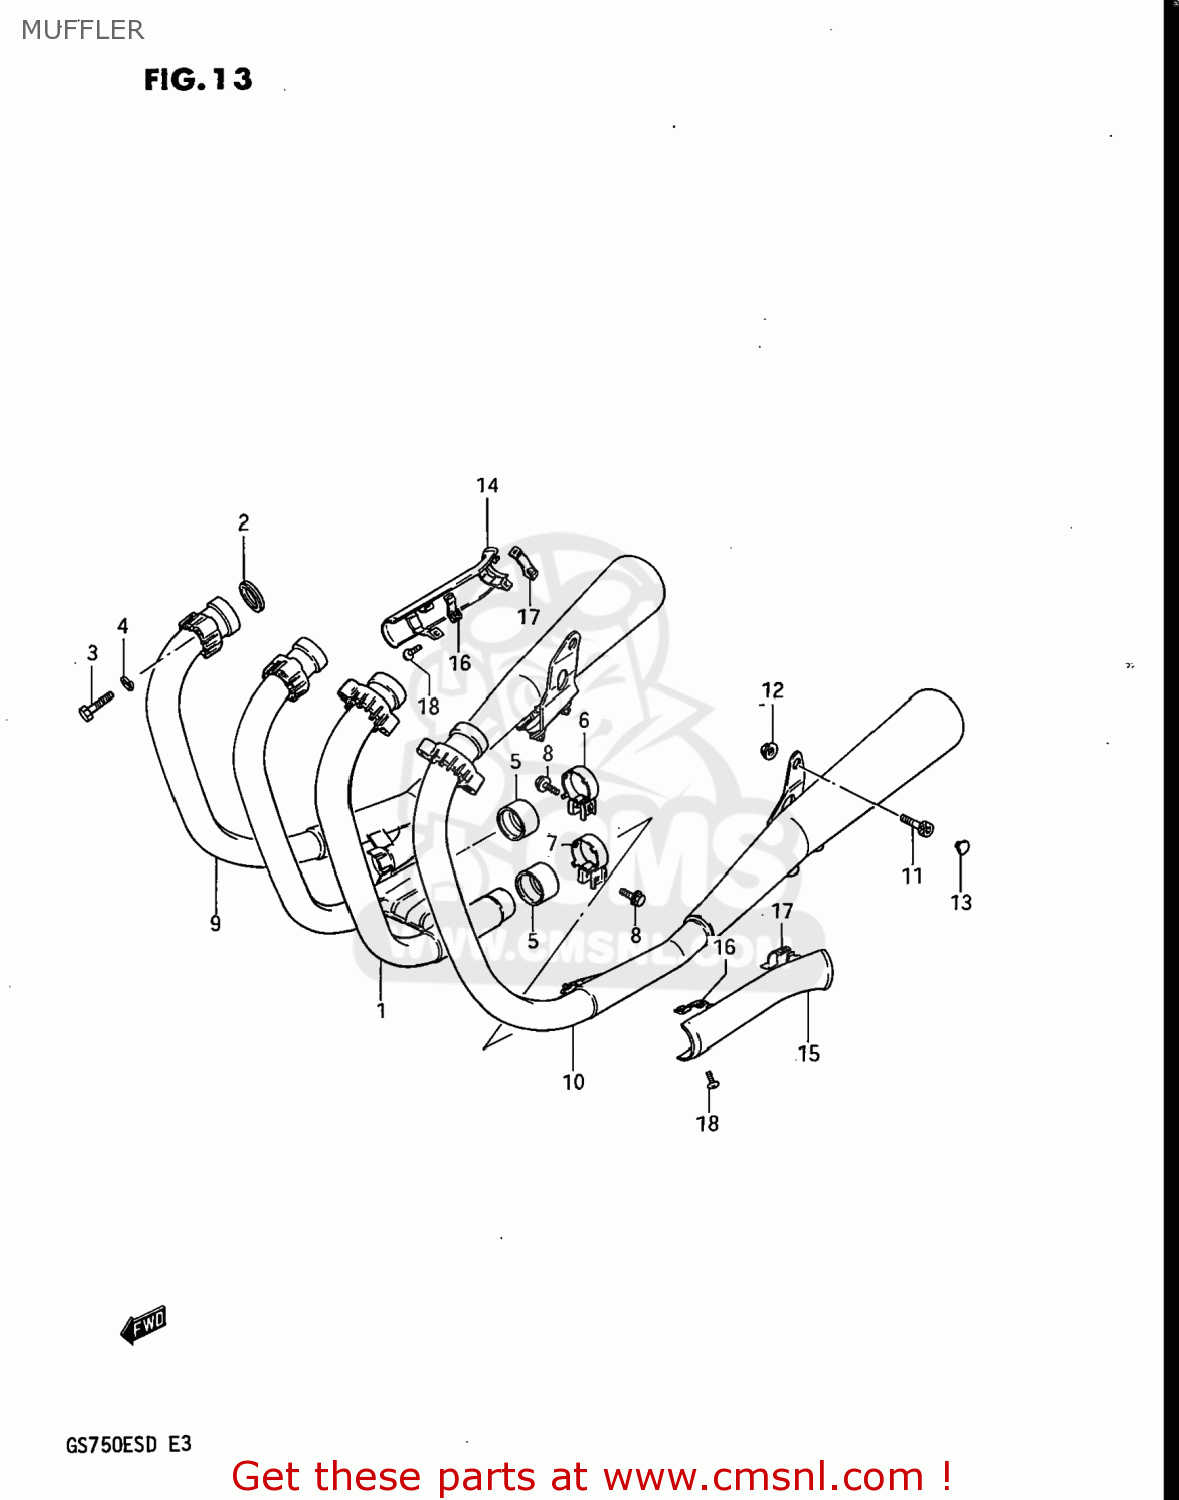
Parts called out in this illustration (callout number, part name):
1	PIPE,EXHAUST
2	GASKET,EXHAUST PIPE (NAS)
3	BOLT 8X40
4	LOCK WASHER
5	CONNECTOR,MUFFLER
6	CLAMP,MUFFLER CONNECTOR
7	CLAMP,MUFFLER CONNECTOR
8	BOLT
9	MUFFLER ASSEMBLY
10	MUFFLER ASSEMBLY
11	BOLT
12	NUT
13	CAP
14	COVER,MUFFLER,RIGHT
15	COVER,MUFFLER,LEFT
16	CLAMP,MUFFLER COVER
17	CLAMP,MUFFLER COVER
18	SCREW
